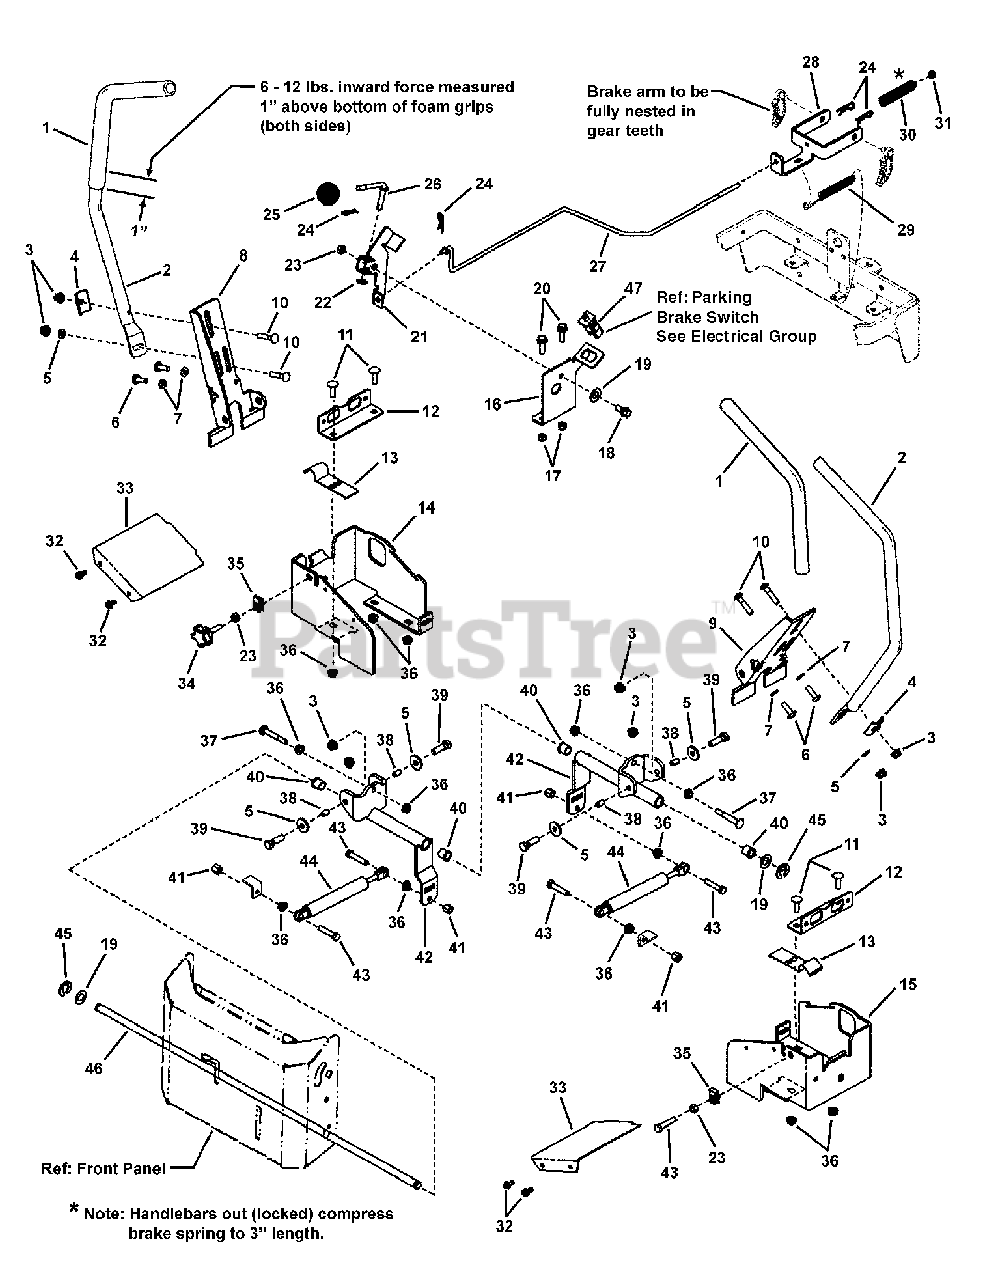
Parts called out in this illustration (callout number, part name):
1	GRIP, Foam Handle Bar
2	TUBE, Handle
3	NUT, 5/16-18 Hex Flange Nyloc
4	CLAMP, Tube, Saddle
5	WASHER, Flat, 5/16
6	SCREW, Truss Head Torx, 5/16-18 x 7/8
7	LOCKWASHER, Spring 5/16
8	BRACKET, Tube Mount LH
9	BRACKET, Tube Mount RH
10	BOLT, Carriage 5/16-18 x 1-3/4, GR5
11	BOLT, Carriage, 5/16-18 x 1, GR5
12	BRACKET, "L" Switch
13	CLIP, Brake
14	BRACKET, Mounting Handle Pivot, RH
15	BRACKET, Mounting Handle Pivot, LH
16	BRACKET, Brake Pivot- ZT
17	NUT, Hex Nyloc, 5/16-18-3B
18	BOLT, Shoulder, 5/16-18
19	WASHER, Flat, 1/2
20	BOLT, Hex Flange Lock, 5/16-18 x 1
21	ARM, Brake Pivot- ZT
22	WASHER, Flat, 3/8
23	NUT, Hex Jam, 5/16-18
24	HAIR PIN
25	KNOB, w/5/16-18 NILN (Brake/Clutch)
26	ROD, Park Brake- ZT (5/16-18 thread)
27	ROD, Manual Parking Brake (1/4-20 threads)
28	BRACKET, Dual Brake
29	SPRING, Extension
30	SPRING, Compression
31	NUT, Hex Flange Nyloc, 1/4-20
32	CAPSCREW, Hex Washer Head, 1/4-20 x 1/2
33	COVER, Lower Handle
34	KNOB, 5/16-18 x 1-1/4" Extension Thread
35	NUT, 5/16-18 Speed (Lug Type .050/.200, Black)
36	NUT, Hex Flange Lock, Small, 5/16-18
37	BOLT, Carriage, 5/16-18 x 2-1/4, GR5
39	CAPSCREW, Hex Head, 5/16-18 x 1-1/4, GR5
41	NUT, Hex Lock, ESNA Light, 5/16-18
42	PIVOT CONTROL
43	CAPSCREW, 5/16-18 x 1-1/2, GR5
44	SHOCK ABSORBER
45	RING, Klipring Extension (for .500 Dia. Shaft)
46	SHAFT, Cross
47	SWITCH, Push Button
